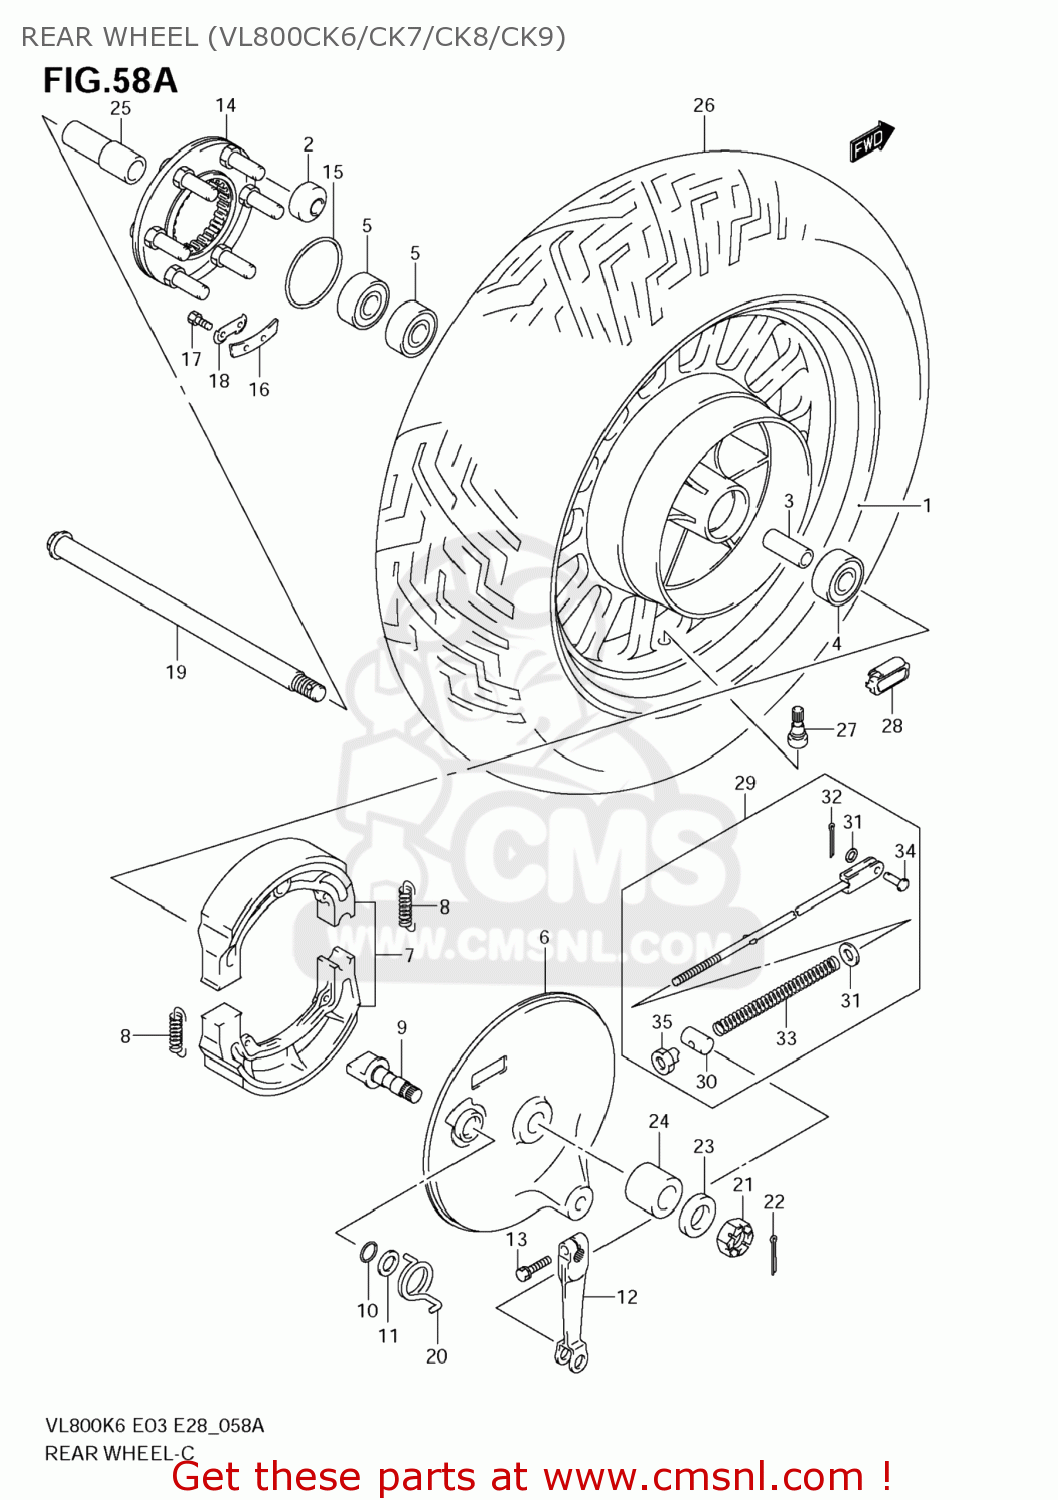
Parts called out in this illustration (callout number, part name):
1	WHEEL,RR(15M/CXMT4.00)
2	BUSH
3	SPACER(17.3X25X99)
4	BEARING
5	BEARING
6	PANEEL.REMANKER
7	SHOE SET,BRAKE (NAS)
8	SPRING,BRAKE SHOE
9	CAM,RR BRAKE
10	O RING(D:2.4,ID:14.8)
11	WASHER(15.5X24X1.6)
12	LEVER,RR BRAKE CAM
13	BOLT
14	JOINT ASSY,RR HUB DRIVEN
15	O RING(D:2.1,ID:65)
16	WASHER,THRUST(T:1.6)
17	BOLT(6X16)
18	WASHER
19	AXLE,RR
20	SPRING
21	NUT
22	PIN
23	WASHER(17X30X3.2)
24	SPACER,RR AXLE,R
25	SPACER,RR AXLE,L
26	TIRE,RR(170/80 15M/C 77H)
27	VALVE ASSY,WHEEL RIM(TR412)
28	WEIGHT,WHEEL BALANCE 10G
29	ROD ASSY,RR BRAKE
30	PIN(13X18)
31	WASHER
32	PIN
33	SPRING
34	PIN(L:13.5)
35	NUT
